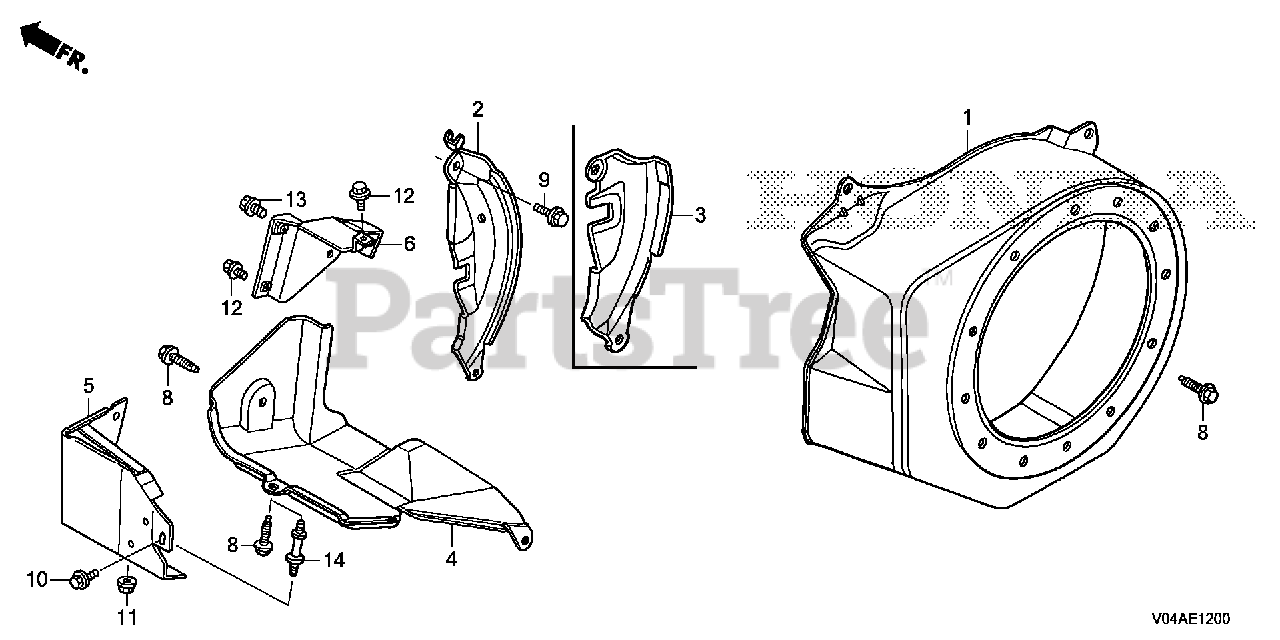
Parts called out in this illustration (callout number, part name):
1	COVER, FAN *R280* (POWER RED)
3	PLATE, SIDE (STARTER MOTOR)
8	BOLT, FLANGE (6X12) (CT200)
9	BOLT, FLANGE (6X25) (CT200)
